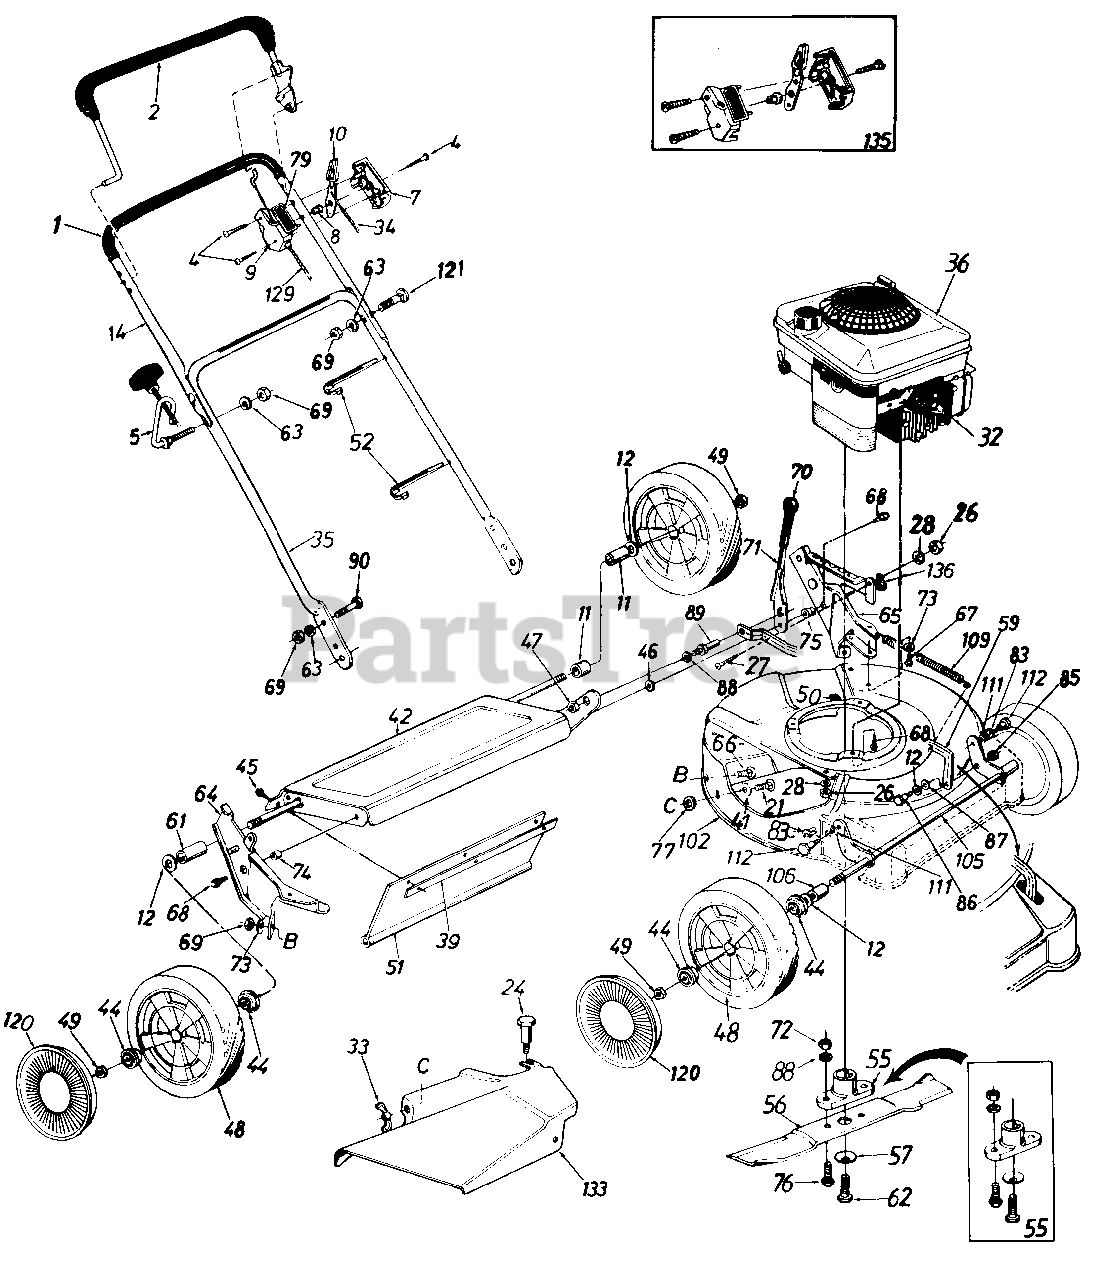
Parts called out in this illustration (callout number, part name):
1	Grip
2	Control Handle Ass'y.-L.H.
4	Truss Mach. Scr. #12 x 1.50" Lg.
5	Rope Guide Bolt
7	Control Panel Half
8	Control Disc Pin
9	Clutch Panel Half
10	Throttle Control Lever
11	Spacer .526" l.D. x .690" O.D. x .640" Lg.
12	Fl-Wash. .510" I.D. x .75
14	Upper Handle
21	Carriage Bolt 1/4-20 x .62
24	Shoulder Bolt .312 Dia. x .18 Lg. Special
26	Hex Nut 1/4-20 Thd.*
27	Truss Mach. Scr. 1/4-20 x 75" Lg.
28	L-Wash. 1/4" I.D.*
32	Spark Plug Insulator
33	Wing Nut w/Washer
34	Throttle Control Wire 58"
35	Lower Handle
36	Engine
39	Retaining Strip
41	Fl-Wash. .344" I.D. x .62"
45	Hex AB-Tap Scr. 1/4 x .62"
46	Fl-Wash. .38" I.D. x 1.0"
47	Hex Jam Nut 3/8-24 Thd.
48	Wheel Ass'y.-Comp. 3" x 2"
49	Hex L-Nut 1/2-20 Thd.
51	Rear Flap 3.75" x 17.30" Lg.
52	Cable Tie
55	Blade Adapter Kit
56	21" Blade
57	Bell-Wash..46" I.D.
59	Height Adj. Connecting Arm
61	Sleeve .526" l.D. x .69"
62	Hex Bolt 7/16-20 x 1.5" Lg. (Grade 5)
63	L-Wash. 5/16" l.D.*
64	R.H. Handle Wheel Brkt. Ass'y.
65	L.H. Handle Wheel Brkt. Ass'y.
66	Carriage Bolt 5/16-18 x .62
67	Hex Wash. Hd. B-Tap Scr. 5/16-18
68	Hex Wash. Hd. TT-Tap Scr. 3/8-1 6
69	Hex Nut 5/16-18 Thd.*
71	Height Adj. Lever
72	Hex Nut 3/8-24 Thd.
73	Bell-Wash. 5/16" I.D.
74	Spacer .383" I.D. x 503" O.D.
75	Shld. Spacer 500" Dia.
76	Hex Bolt 3/8-24 x 1" Lg.
77	Bolt Retainer 1/4 X .50" O.D.
79	Control Label
83	Flanged Nyliner Brg.
85	Hex Jam Nut 3/8-16 Thd.
86	Shld. Bolt .50" Dia. x .295"
87	Bell-Wash. .515" l.D. x 1.0" O.D.
88	L-Wash. 3/8" I.D.*
89	Shld. Pin 3/8-24 x 1.43" Lg
90	Truss Mach. Scr. 5/16-18 x
106	Sleeve .526" I.D. x .690" O.D. x .880" Lg.
109	Extension Spring 8" Lg.
111	Intern. L-Wash. 3/8 I.D.*
112	Shld. Bolt .575" Dia. x .42"
120	Hub Cap
121	Curved Carr. Bolt 5/16-18 x 1.38" Lg.
129	Control Cable 46" Lg.
133	Side Chute Deflector Ass'y.
135	Kit-Control Housing Comp.
